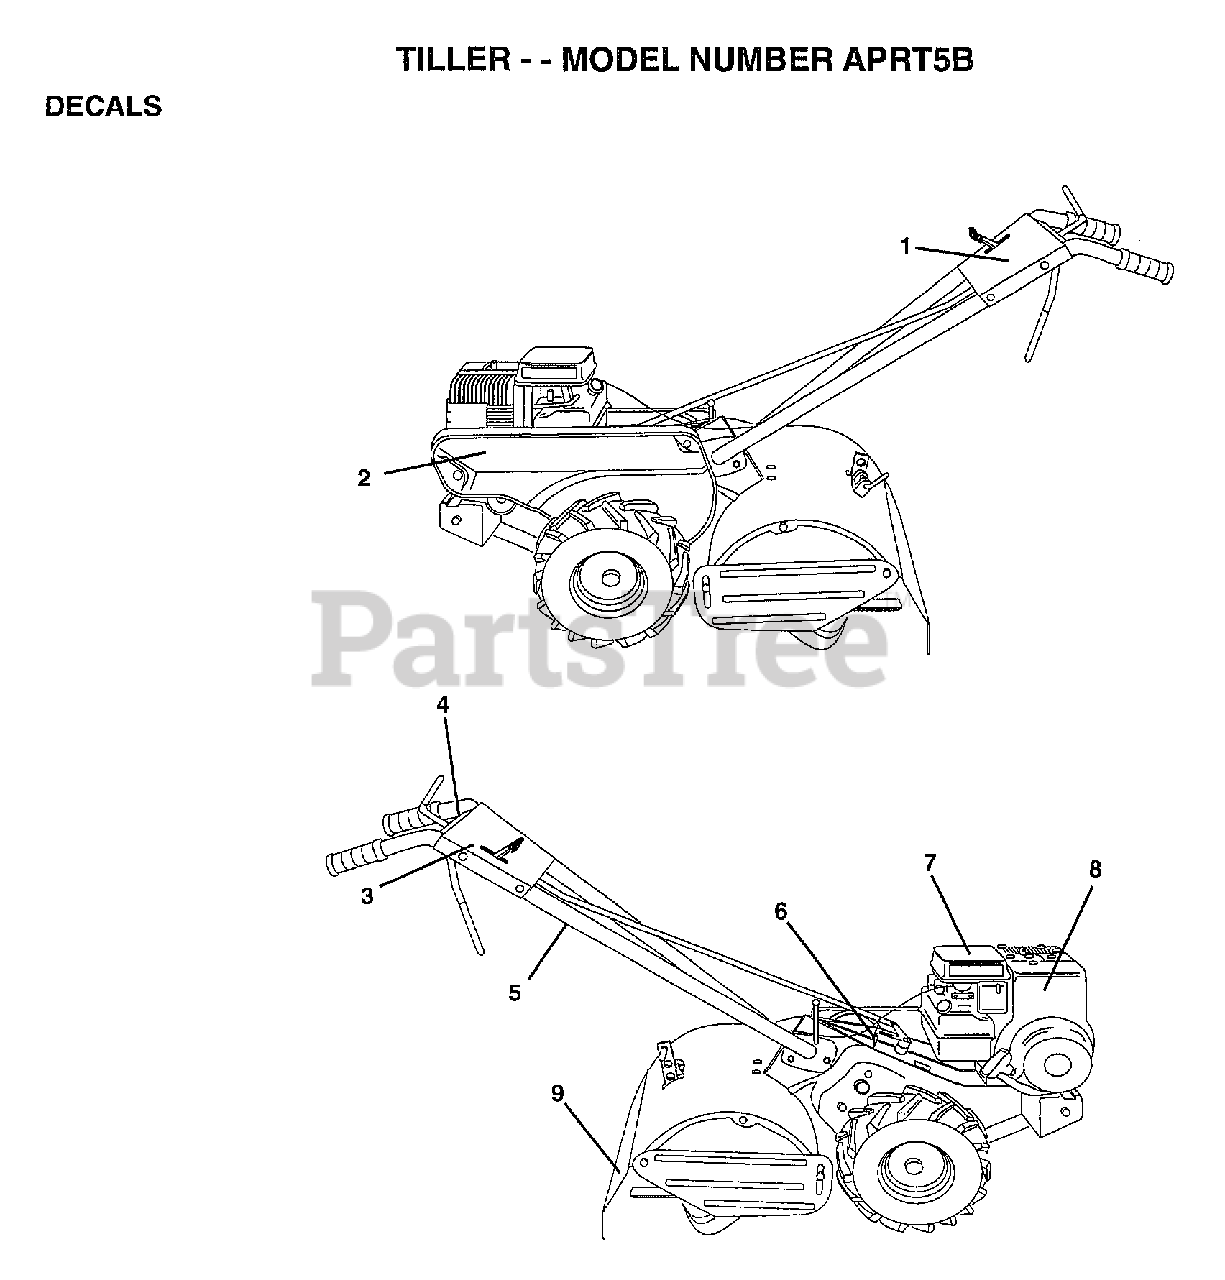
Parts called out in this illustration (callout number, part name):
1	DECAL.CNTRL.PNL.A
2	DECAL.GUARD.BELT
3	DECAL, PANEL CONTROL
5	DECAL TI
7	DECAL TI
8	DECAL, BRIGGS & STRATTON
